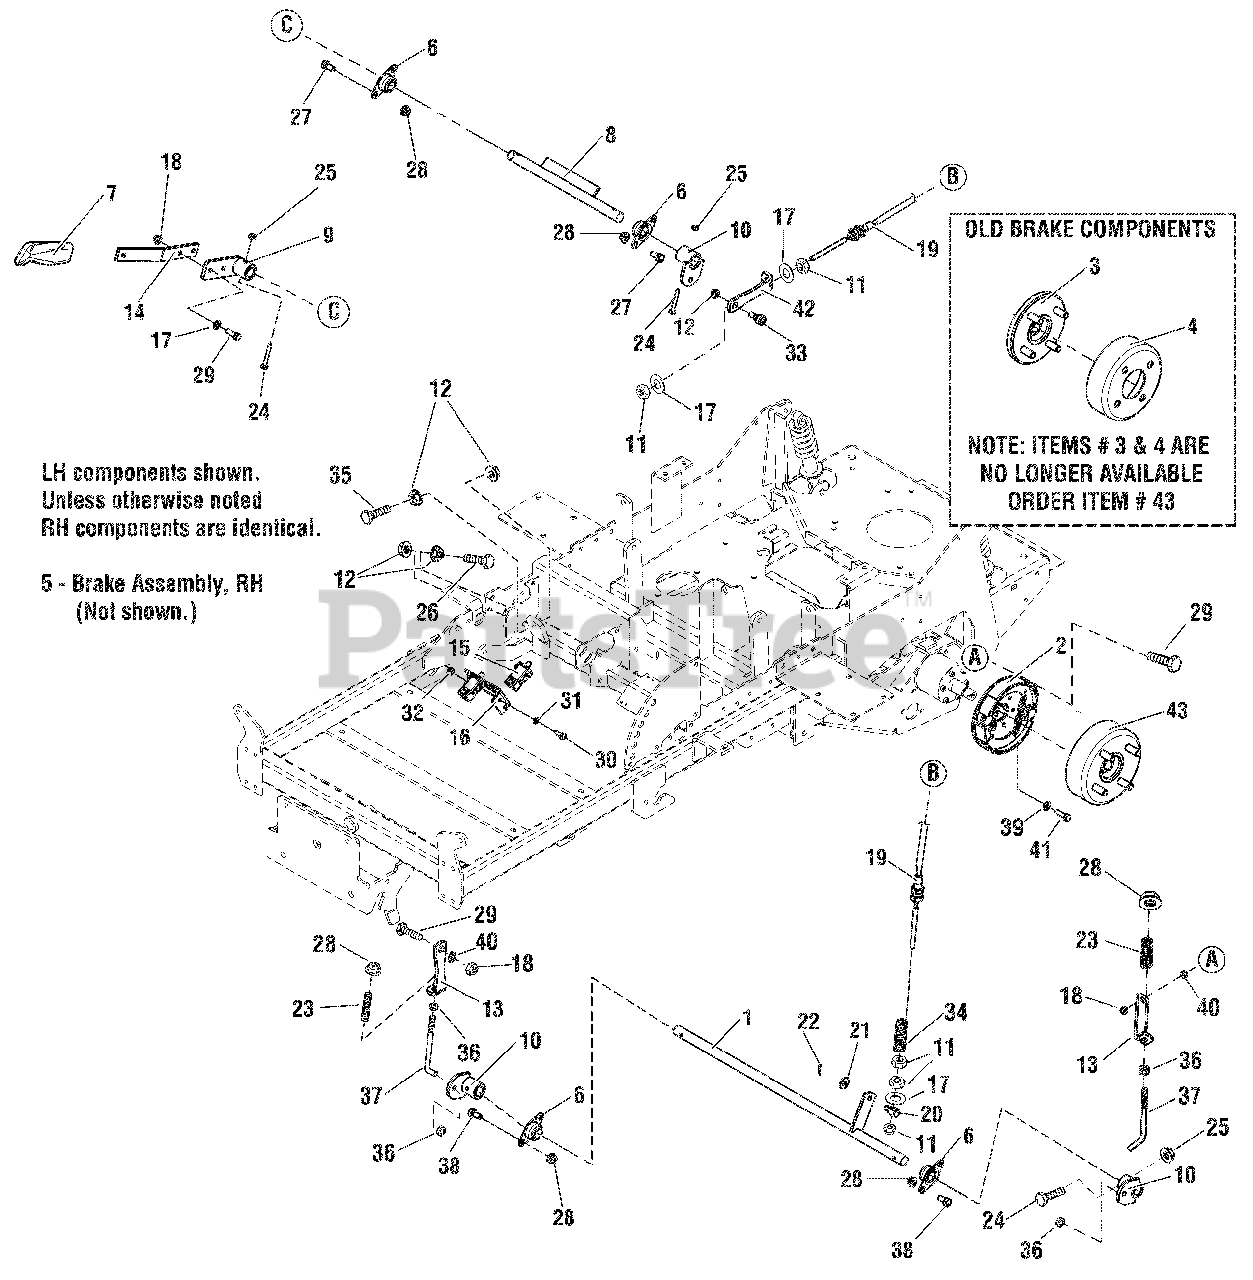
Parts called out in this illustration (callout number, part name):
1	WELD, SHAFT, REAR BRAKE - RED
2	BRAKE ASSY, LH # HGB-BPW1-2X.
3	HUB, W/STUD, 1TPR 800645
4	BRAKE DRUM
6	BEARING, BRONZE FLANGE, 3/4
7	GRIP, BLACK FLEXIBLE
8	WELD,SHAFT, BRAKE LEVER
9	WELD, MOUNT, BRAKE LEVER
10	WELD, PIVOT LINKAGE MOUNT
11	NUT, 5/16-24 HEX
12	NUT, 3/8-16 HEX SERRATED FLANGE
13	LINK, BRAKE LOCK - RED
14	HANDLE, BRAKE LEVER
15	SWITCH, PLUNGER, NO/NC SNAP-IN
16	BRACKET, SWITCH MOUNT
17	WASHER, 5/16" SAE
18	NUT, 5/16-18 HEX NYLOCK FLANGE
19	* CABLE, PARKING BRAKE
20	ADJUSTER, BRAKE LINKAGE
21	WASHER, 5/16 USS
22	PIN, 3/32 X 0.750, COT, ZINC/CLEAR
23	SPRING, COMP, .428ID X 2.50LG X .155WR
24	BOLT, 1/4-20 X 1-1/2, GD5
25	NUT, 1/4-20 HEX SIDE LOCK
26	BOLT, 3/8-16 X 1-3/4" GD5 CZ
27	BOLT, 3/8-16 X 3/4" GD5 CZ
28	NUT, 3/8-16 HEX NYLOCK FLANGE
29	BOLT, 5/16-18 X 1 GD5 YZ
30	BOLT, 1/4-20 X 5/8 GD5 YZ
31	WASHER, 1/4 SAE
32	NUT, 1/4-20 HEX SERR. FLANGE
33	BOLT, 3/8-16 X 3/8, 1/2 SHOULDER
34	SPRING, COMPRESSION, 5-1/2
35	BOLT, 3/8-16 X 2 GD5 TFL CZ
36	COLLAR, 3/8 SET
37	ROD, BRAKE ADJUSTMENT
38	BOLT, 3/8-16 X 1" GD5 CZ
39	WASHER, 1/4 LOCK
40	SPACER, .38 X .50 X.27
41	CAPSCREW, HEX HEAD M6-1.0X 14MM
42	LINK, BRAKE LOCK - RED
43	BRAKE DRUM, 4-BOLT
